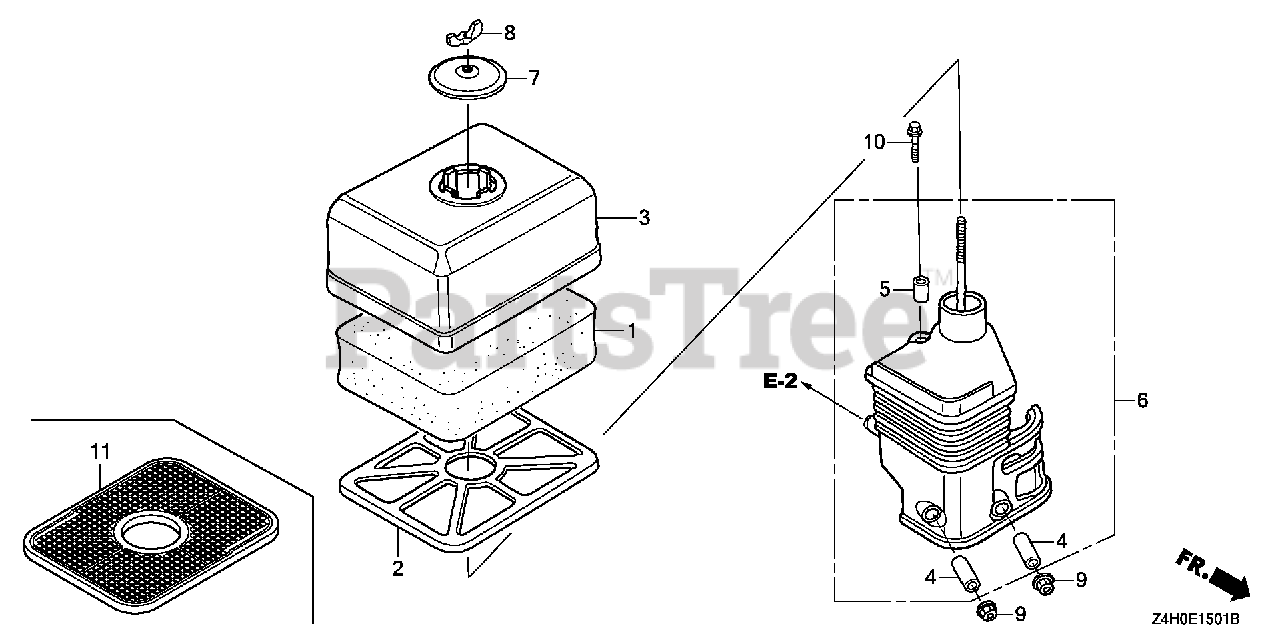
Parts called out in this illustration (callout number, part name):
1	ELEMENT, AIR CLEANER (SEMI-DRY)
2	GRID, AIR CLEANER (SEMI-DRY)
3	COVER, AIR CLEANER (SEMI-DRY)
4	COLLAR, AIR CLEANER
5	COLLAR B, AIR CLEANER
6	ELBOW, AIR CLEANER
7	CAP, CLEANER
8	WINGNUT, TOOL BOX SETTING
9	NUT, FLANGE (6MM)
10	BOLT, FLANGE (6X20)
